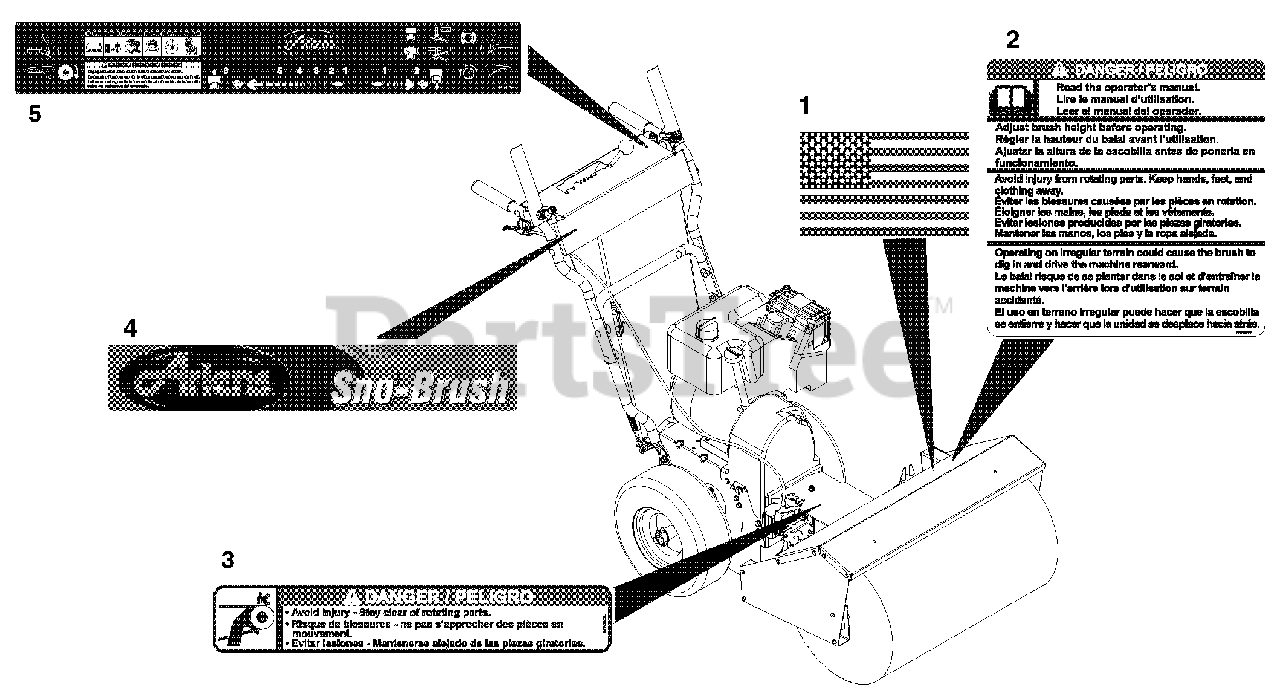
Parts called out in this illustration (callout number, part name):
1	DECAL, AMERICAN FLAG
2	DECAL, DANGER - POWER BRUSH
3	DECAL- DANGER
4	DECAL,DASH SNO-BRUSH
5	DECAL, CONTROL, SNO-BRUSH 920
